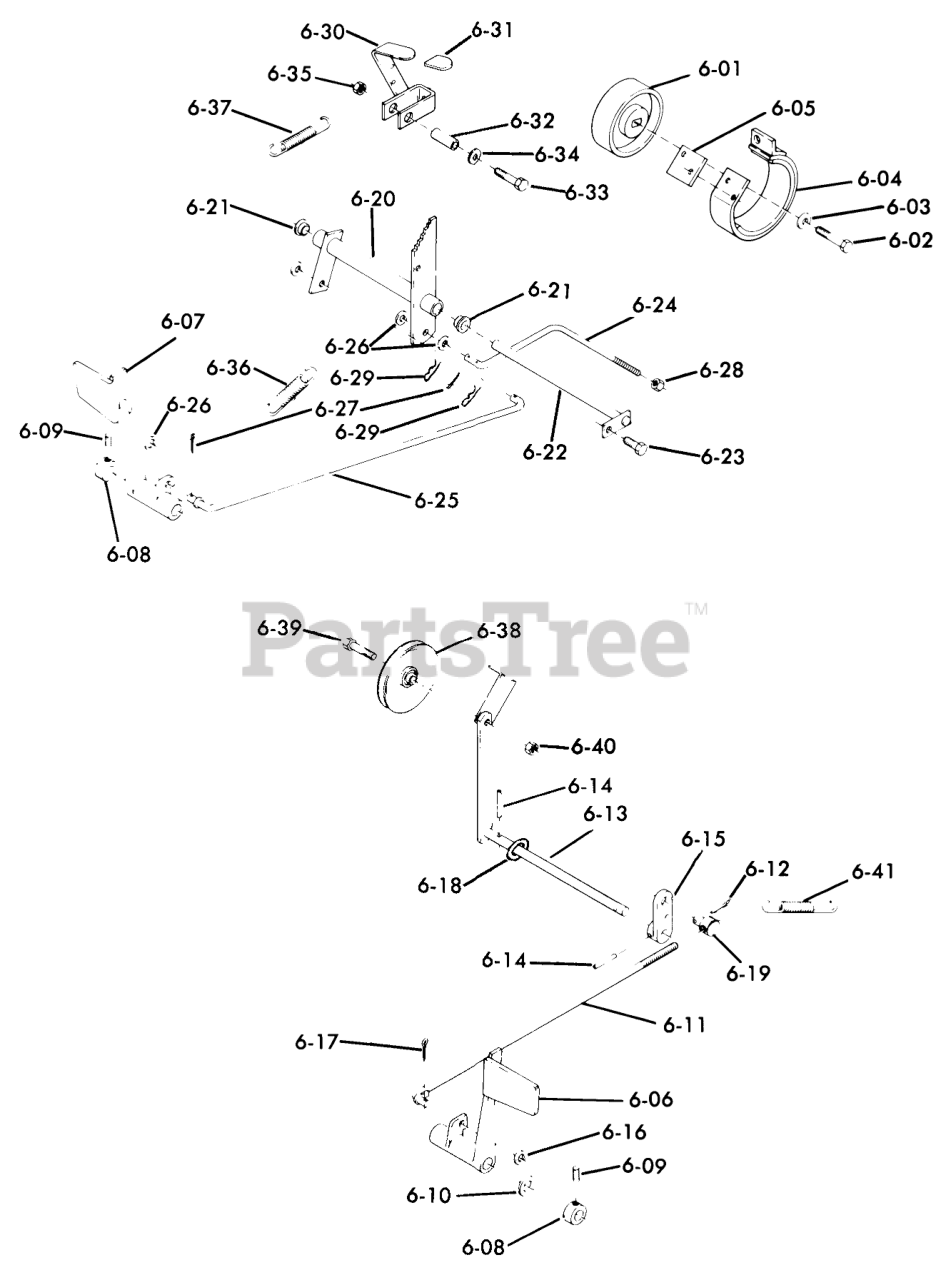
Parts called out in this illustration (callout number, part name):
6-01	Brake Drum
6-02	Bolt
6-03	WASHER
6-04	BRAKE BAND ASM
6-04	H H C S
6-04	Washer
6-05	Plate-Stop
6-06	Clutch Pedal
6-07	PEDAL-BRAKE R
6-08	Collar
6-09	SCREW-SET
6-10	WASHER-BOWED
6-11	ROD AND GUIDE ASM
6-13	Idler Arm Assembly
6-14	PIN-SPIROL
6-15	Clutch Pivot Arm
6-16	WASHER-NYLON
6-17	Pop Rivet
6-18	SHIM-WASHER
6-20	Bellcrank Assy
6-21	BUSHING-FLANGED
6-22	Rod Assy
6-23	SCREW
6-24	Brake Rod
6-26	WASHER-NYLON
6-27	Pop Rivet
6-28	NUT
6-29	Hairpin
6-30	Brake Lever Assy
6-31	GRIP
6-32	SPACER
6-33	Bolt
6-34	Washer
6-35	LOCKNUT-FLANGE
6-36	Spring
6-37	SPRING-EXTENSION
6-38	PULLEY-IDLER
6-39	HEX HD CAP SCREW
6-40	Nut
6-41	Spring
